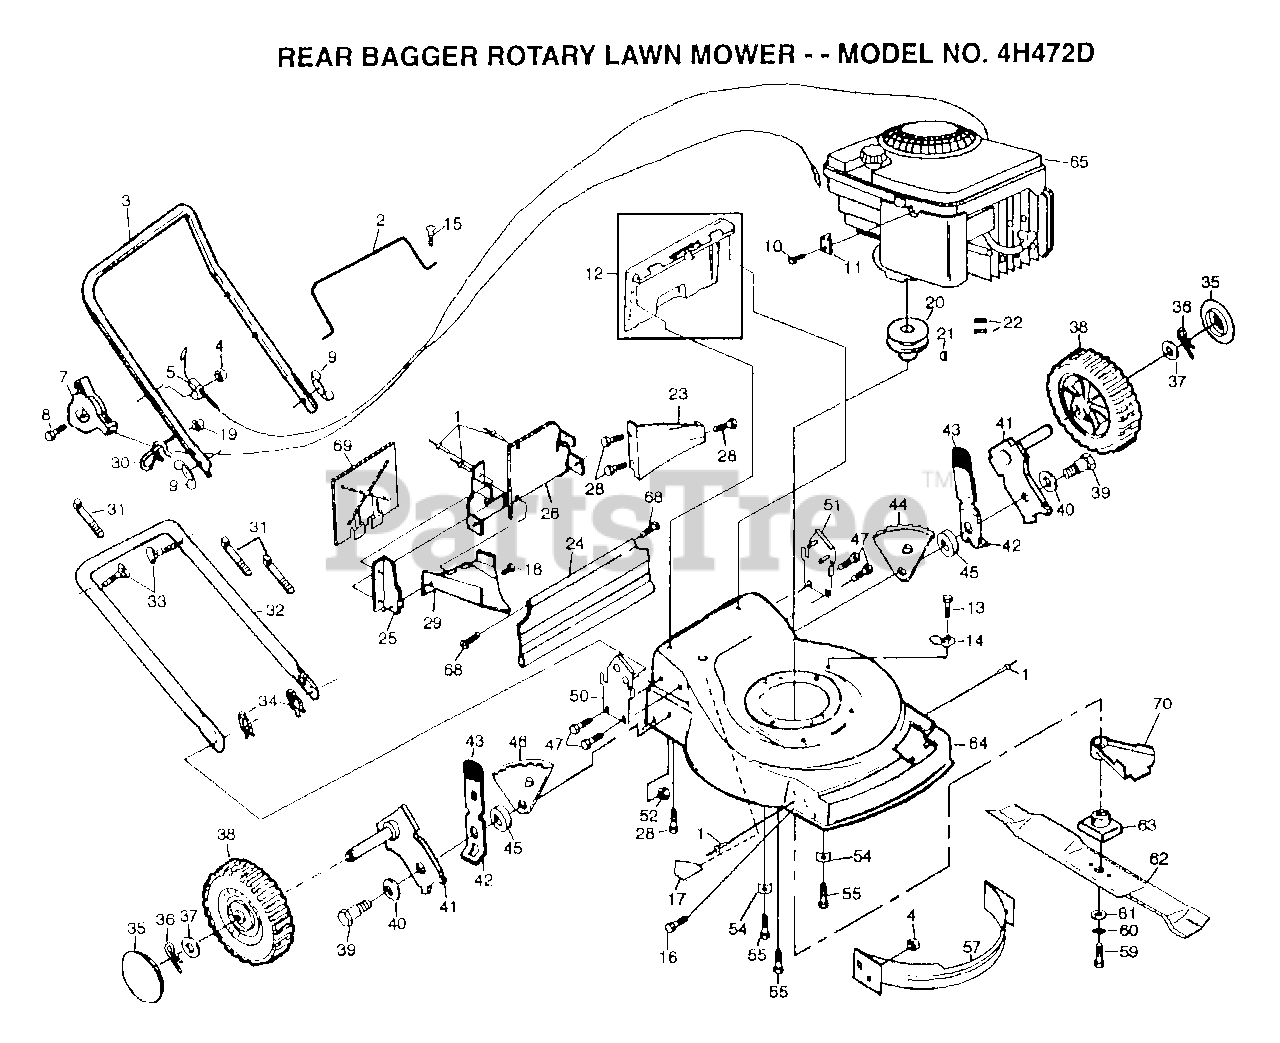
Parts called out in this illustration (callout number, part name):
1	BLIND RIVET
2	CONTROL BAR
5	"CABLE,ENG ZONE CO"
7	"CONTROL, THROTTLE"
8	SCREW.HXHD.WASH.
9	"NUT,WING PM"
10	SCREW PM
11	CABLE CLAMP
12	KIT.DOOR.REAR.22
13	TAPPING SCREW
14	GUIDE CLIP PM
15	"SCREW,PAN HD"
16	SCREW
17	DECAL HYT
18	SCREW PM
19	NUT
20	ENGINE.PULLEY.FWG
21	HI PRO KEY PM
22	SCREW
23	REAR BAFFLE
24	SKIRT.REAR.FGD.22
26	PLATE.BACK.22RD
28	SCREW
29	DISCHARGE BAFFLE
30	ROPE GUIDE
33	BOLT.HANDLE.LM
34	HAIRPIN COTTER
35	HUB CAP
36	RETAINER CLIP PM
37	WASHER
39	BOLT SHLD 3/8-16
40	"WASHER, BELLEVIL."
41	AXLE ARM
42	SPRING SELECTOR
43	KNOB PM
44	BRACKET.ADJ.9.LH
46	BRACKET.ADJ.9.RH
47	SCREW
52	LOCKNUT PM
55	SCREW
59	SCREW
60	LOCKWASHER
61	"WASHER,HARDEN"
62	BLADE.20.MULCH.AY
63	ADAPTOR.BLADE.LM
64	KIT.HSG.22RD.FWGD
68	HINGE SCREW
69	MULCHER PLATE
